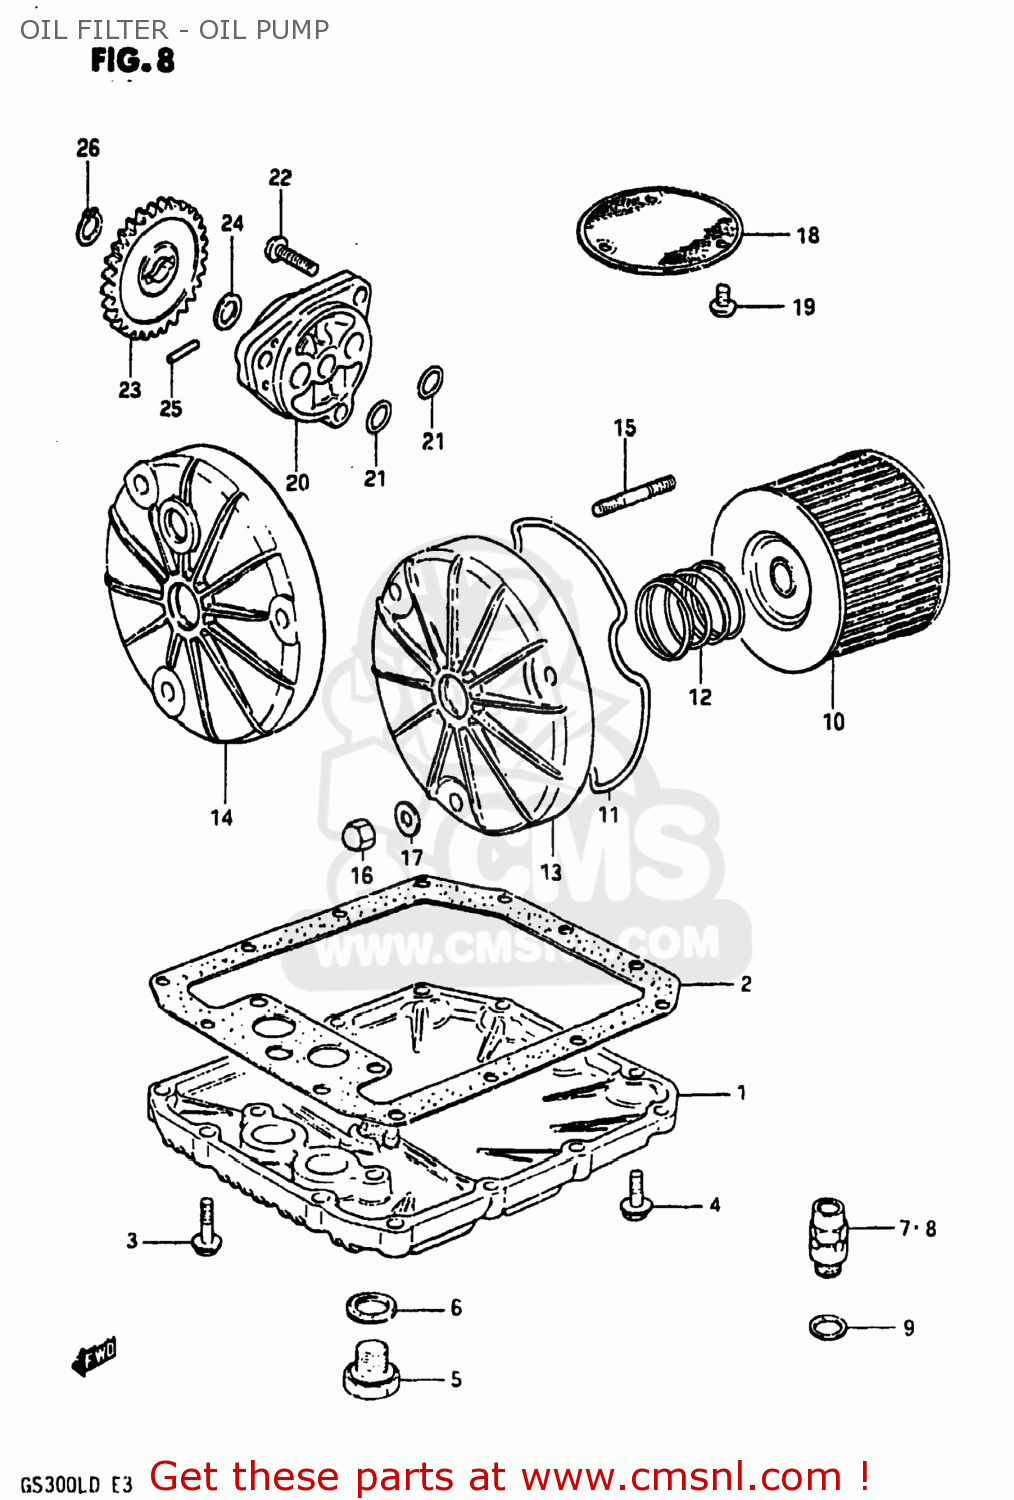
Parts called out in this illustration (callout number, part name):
1	PAN,OIL
2	GASKET,OIL PAN (MCA)
3	BOLT
4	BOLT
5	PLUG
6	GASKET(14X19.2X2) (NAS)
7	REGULATOR ASSEMBLY,ENGINE
8	VALVE ASSEMBLY,OIL RELIEF
9	WASHER
10	FILTER ASSY,ENGINE OIL
11	O RING,OIL FILTER CHAMBER CAP
12	SPRING
13	CAP,ENGINE OIL FILTER
14	CAP,OIL FILTER
15	STUD 6X20
16	NUT
17	WASHER
18	STRAINER,ENGINE OIL
19	SCREW 6X12
20	PUMP ASSY,ENGINE OIL
21	O RING(D:1.9,ID:13)
22	SCREW
23	GEAR,OIL PUMP DRIVEN
24	SHIM
25	PIN(4X15.8)
26	CIRCLIP
